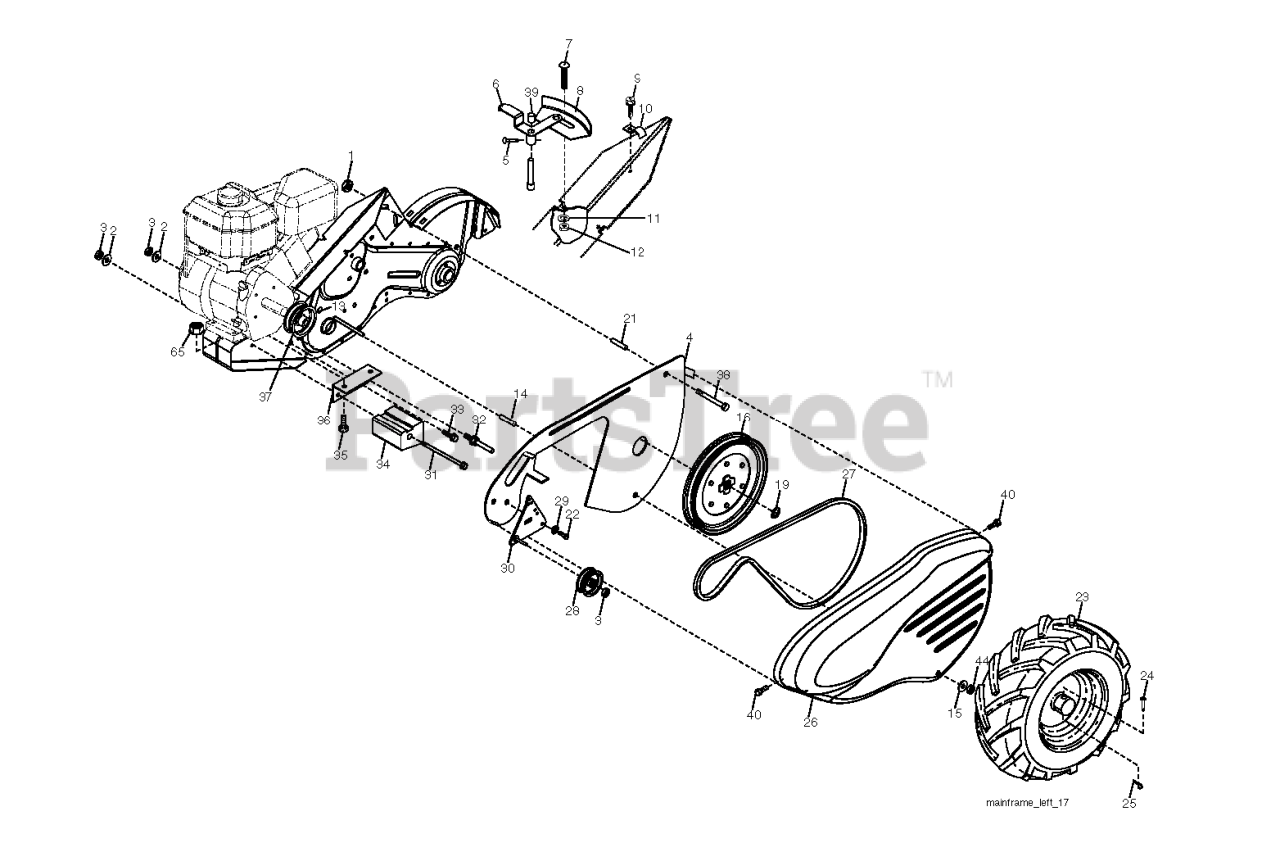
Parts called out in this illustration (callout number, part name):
1	NUT
2	WASHER, LOCK 3/8
3	NUT.HEX.3/8-16UNC
4	SHIELD
5	PIN.SPIROL.FLARED
6	LEVER ASM CRT
8	PANEL.INDICATOR.SHIFT.BLACK
9	TAPPING SCREW
10	CONDUIT.CLIP.PLATED
11	LOCKWASHER
12	NUT
14	SPACER-SPLIT.327 X .42
15	WASHER
16	SHEAVE, TRANSMISSION
19	RETAINING RING LT
21	SPACER CRT
23	TIRE.13X5-6.CHEVRON.TILLER
24	RIVET,DRILLED
25	RETAINER M
26	RP BELT GUARD
27	V-BELT
28	PULLEY-IDLER TI
30	BRACKET.ASM.IDLER.BLACK
31	BOLT.FIN.HEX.3/8-16UNC
32	SHIFT ARM CRT
33	BOLT
34	COUNTERWEIGHT.LH.CRT
35	BOLT
36	BRACKET LH CRT
37	RP.ENGINE PULLEY
38	BOLT
39	CAP.PLUNGER.BLACK
40	SCREW.HEX.WSH.SLT.#10-24X.50
44	NUT.71038.31-18.HEX.NYLOCK
65	LOCKNUT-FLANGE 5/16-18
